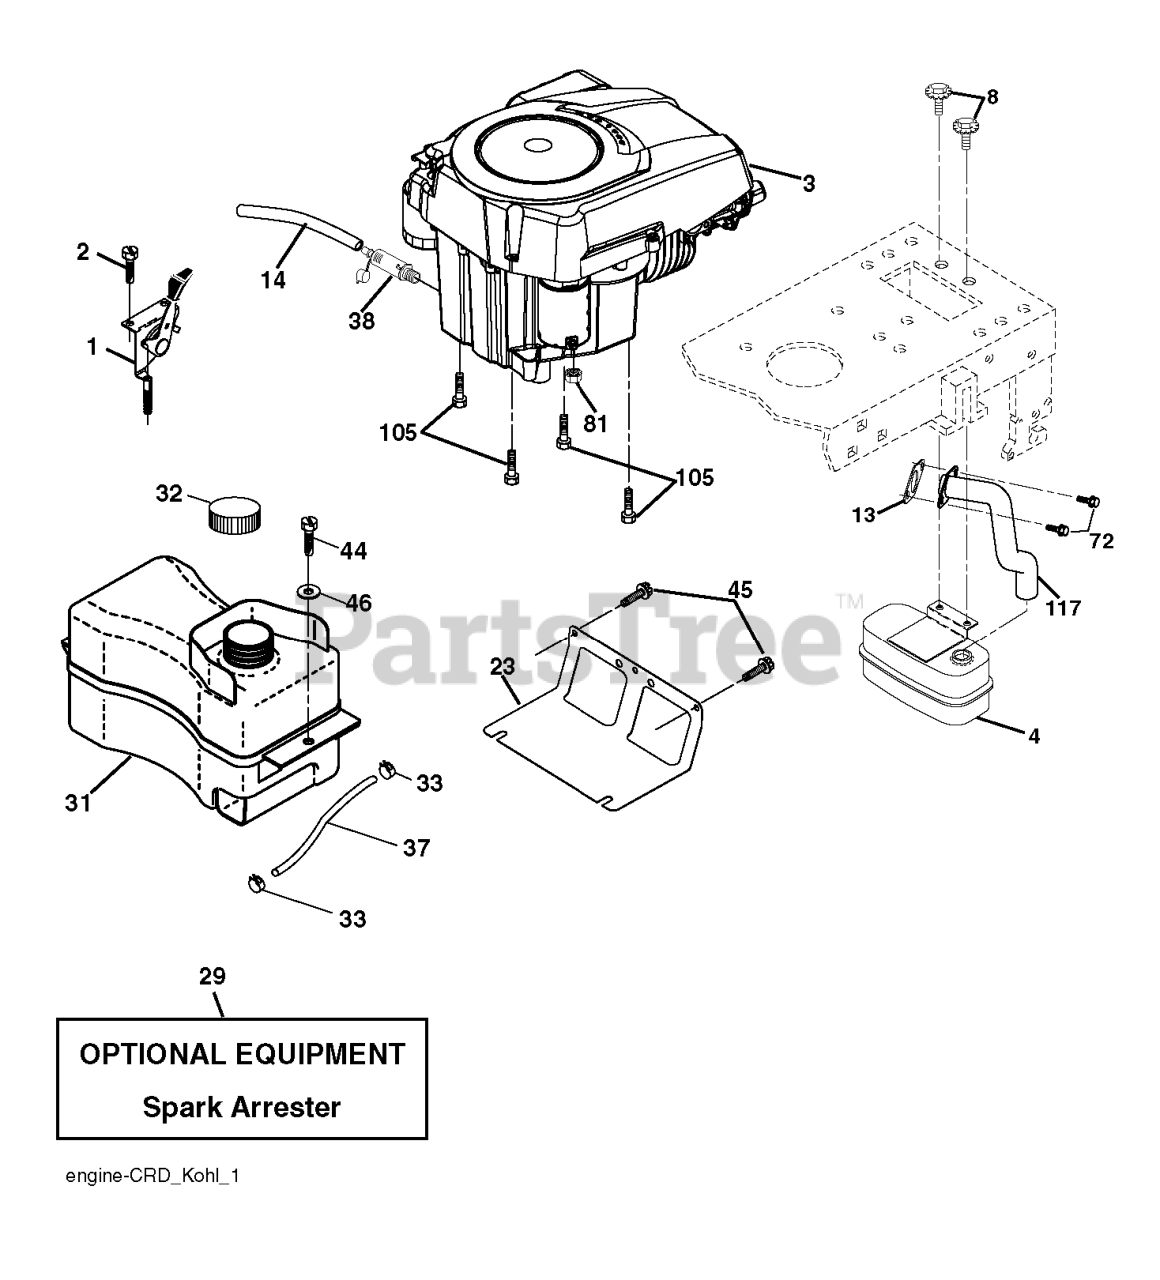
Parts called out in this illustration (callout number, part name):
1	CONTROL.TH/CK.C.
2	SCREW.#10 X 0.750.BOS
4	MUFFLER.SINGLE.CYL.KOHL/B&S
8	BOLT.5/16-18UNCX3/4 W/SEMS.BLK
13	GASKET.EXHAUST.KOHLER
14	TUBE, DRAIN OIL ASM.
23	SHIELD.BROWNING.DBR.GUARD
29	KIT.SPARK ARRESTOR 794945 B&S
31	RP TANK FUEL FRT 1.5 GAL
32	FUEL CAP
33	HOSE CLAMP
37	LINE.FUEL.20
38	PLUG DRAIN OIL EASY
44	SCREW HEXWSHR 1/4-20X3/4
45	SCREW, 3/8-16X3/4
72	SCREW.SOCKET HD.5/16-1
81	NUT
105	SCREW 3/8-16X1
117	RP.TUBE.EXHAUST.KOHL.COURAGE
